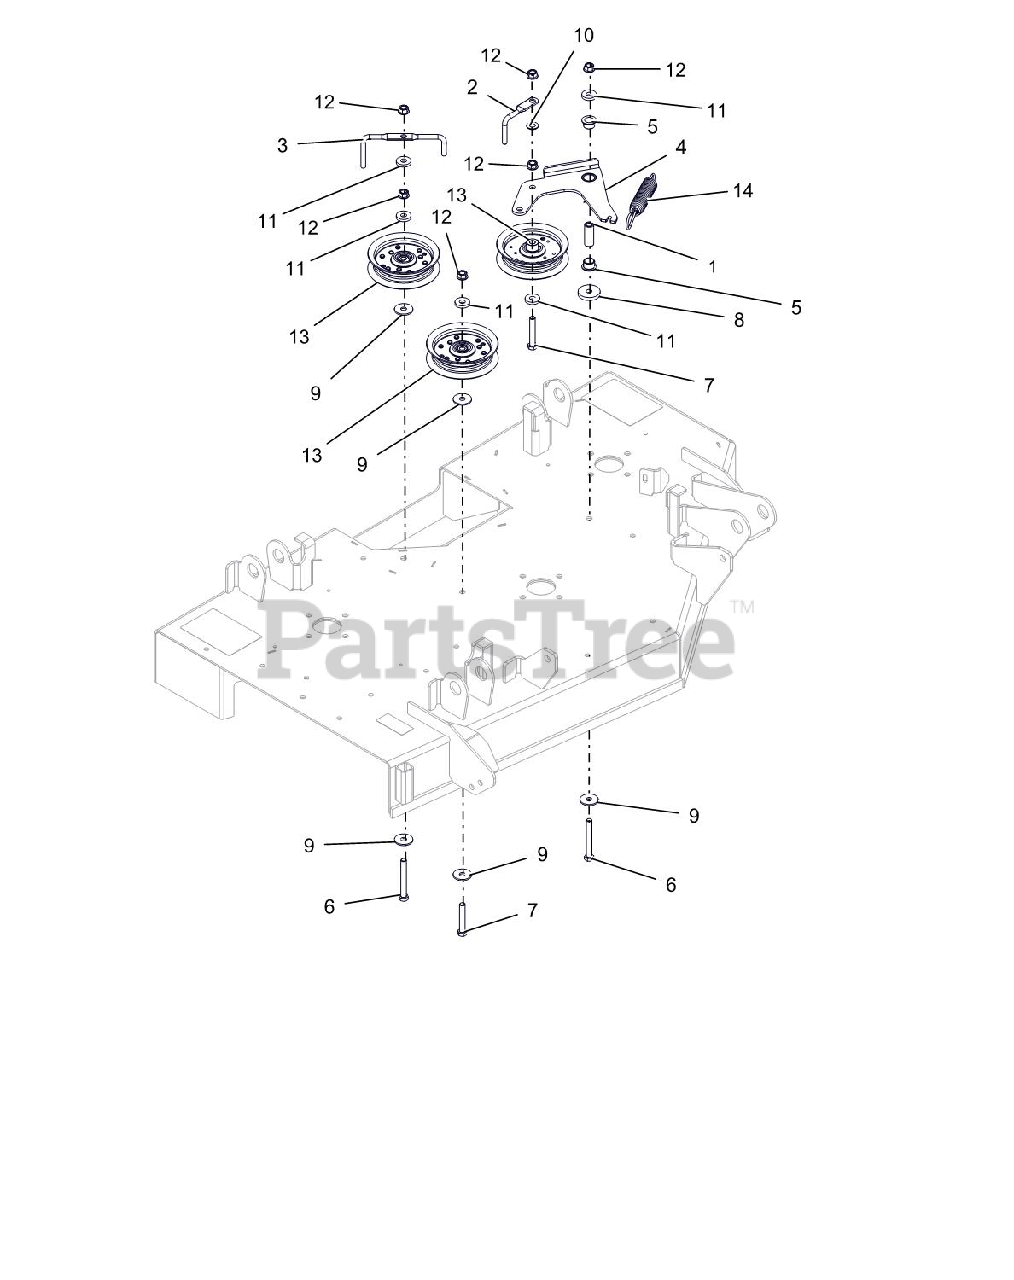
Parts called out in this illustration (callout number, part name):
1	SPACER, .375IDX.625ODX1.66 PM
2	WIREFORM, BELT FINGER
3	BELT FINGER
4	WLDMT, IDLER ARM-42"
5	BSHG-FLG, .625X.750X.500X1.00
6	BLT-HEX .38-16X3.00 GR5 FTH YZ
7	@BLT-HEX .38-16X2.25 GR5 YWZC
8	WSHR,FLT STL.406X1.50X.245YWZC
9	@WSHR-FL-STL .406X1.25X.10 ZC
10	@WSHR-FL-STL.406X.812X.065 YWZ
11	WSHR-FL-STL .406X1.00X.188 YWZ
12	@NUT-LK-TOP-FLG .38-16 YWZC
13	ASM, IDLER 4"
14	SG-TENS .135X.98X6.0 WLD 62
